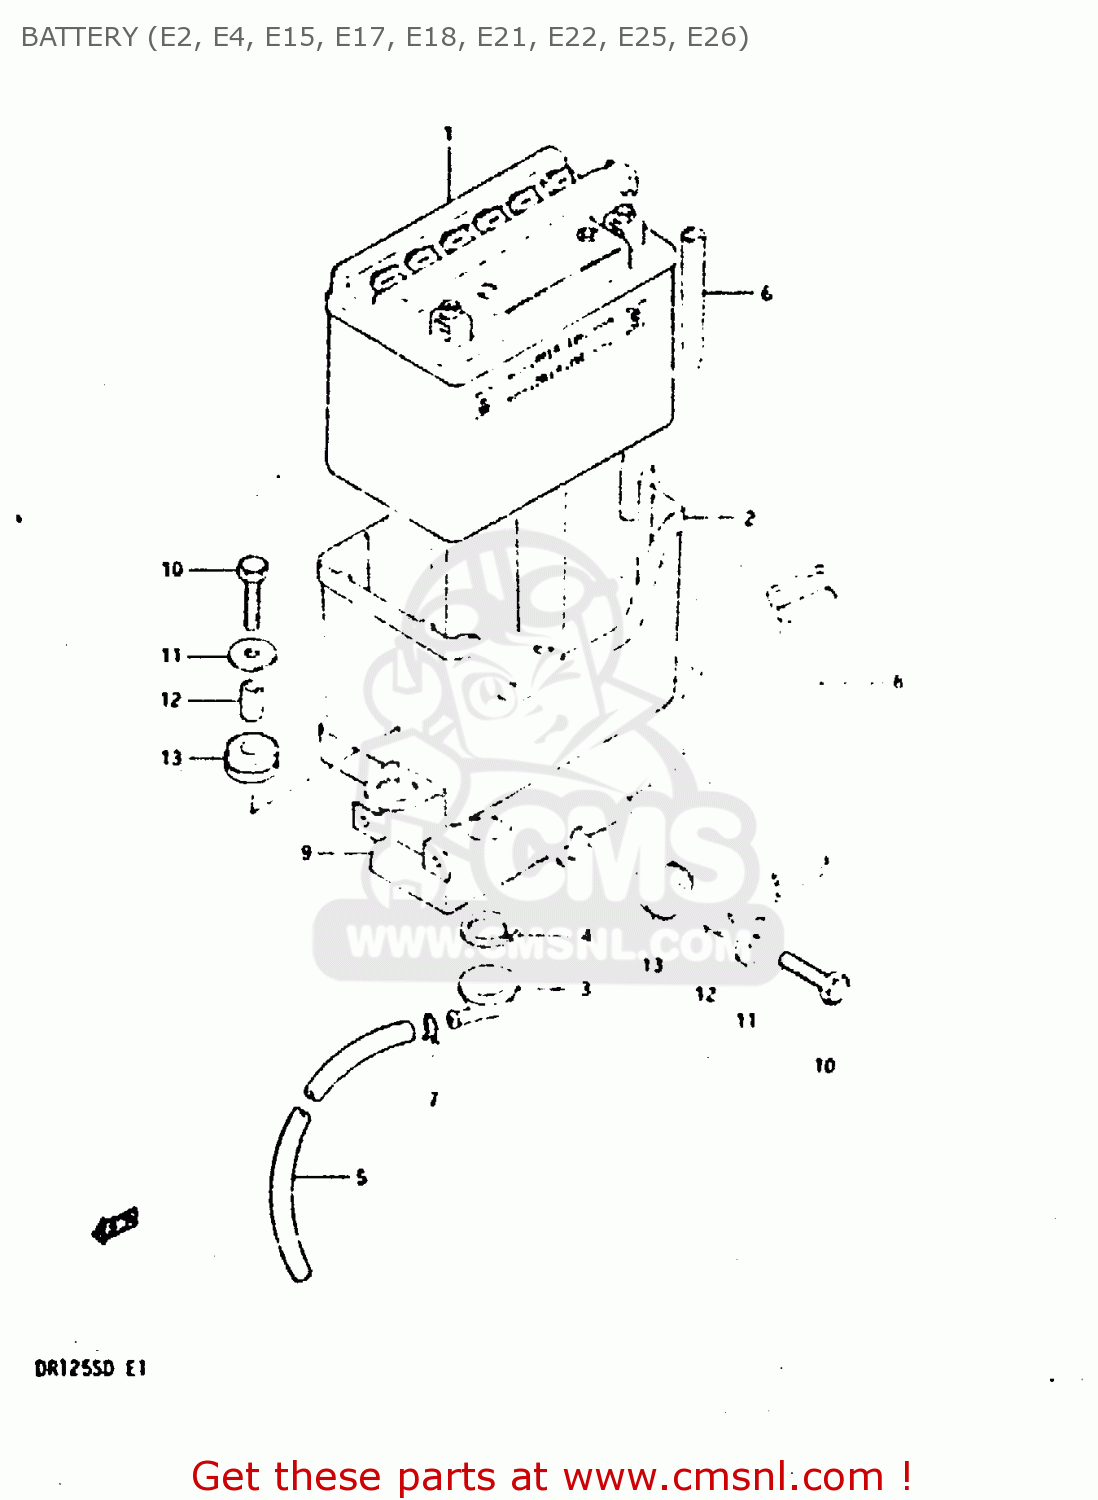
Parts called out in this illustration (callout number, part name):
1	BATTERY ASSY(YB4L-B,12V4.2AH)
2	CASE, BATTERY
3	FUNNEL,BATTERY EXHAUST
4	CIRCLIP
5	HOSE,BATTERY EXHAUST
6	HOSE, EXHAUST (L:45)
7	CLIP
8	BAND
9	HOLDER, BATTERY
10	BOLT, UPPER
11	WASHER (6.5X20X1.2)
12	SPACER(6.1X9X7.5)
13	CUSHION
